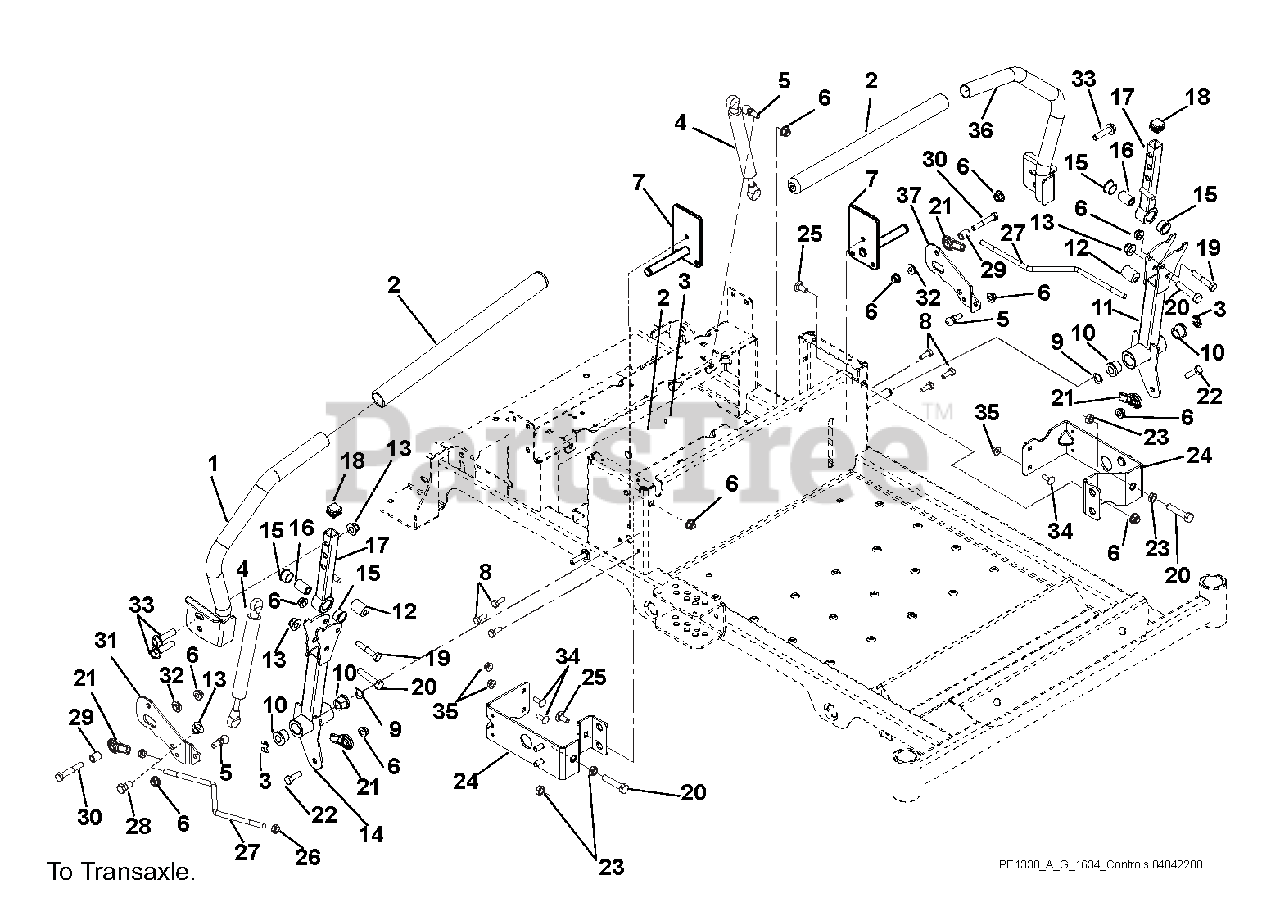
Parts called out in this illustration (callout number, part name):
1	WMT, STEERING HANDLE
2	GRIP, HANDLEBAR 15" FOAM
3	RG-RTNG-EXT .500X.042 (E)
4	DAMPER, STABILUS
5	STUD- BALL
6	@NUT-LK-NYL-FLG .31-18 YWZC
7	WMT, STEERING SHAFT
8	SCR-TAP .25-20X.50 HWH TR YWZ
9	WSHR-WAVE .50X.75X.015 .13FRHT
10	BSHG-FLG .500X.750X.625X.937
11	WMT, LOWER CONTROL ARM
12	BSHG, ECCENTRIC .328X.750X.970
13	@NUT-LK-NYL-FLG .38-16 YWZC
14	WMT, LOWER CONTROL RH
15	BSHG-FLG, .625X.75X.450X.875
16	SPACER, .375X.625X.970 (PM)
17	WMT, UPPER CONTROL ARM
18	CAP PLUG, SQ 3/4-14-20 RIBBED
19	@BLT-HEX .31-18X1.75 GR5 YWZC
20	BLT-HEX .375-16X1.750 FTD YWZC
21	ALIGNABALL, 5/16 RH THREAD
22	@BLT-HEX .31-18X1.00 GR5 YWZC
23	NUT-HEX-JAM .375-16 YWZC
24	WMT, STEERING STOP
25	@BLT-RHDSSQNK .31-18X.75 G5YZ
26	NUT-JAM .31-24 YWZC
27	WIREFORM, STEERING LINK
28	@BLT-HEX .38-16X.75 GR5 YWZC
29	SPACER, .328X.500X.625
30	@BLT-HEX .31-18X2.00 GR5 YWZC
31	PLATE, DAMPER RH
32	BSHG-FLG .316X.430X.225X.750
33	BOLT, SERRATED HEAD .38-16X1.5
34	@BLT-RDHDSQNK .25-20X.75 G5YZ
35	@NUT-LK-NYL-FLG .25-20 YWZC
36	WMT, STEERING HANDLE LH
37	PLATE, DAMPER (LH)
